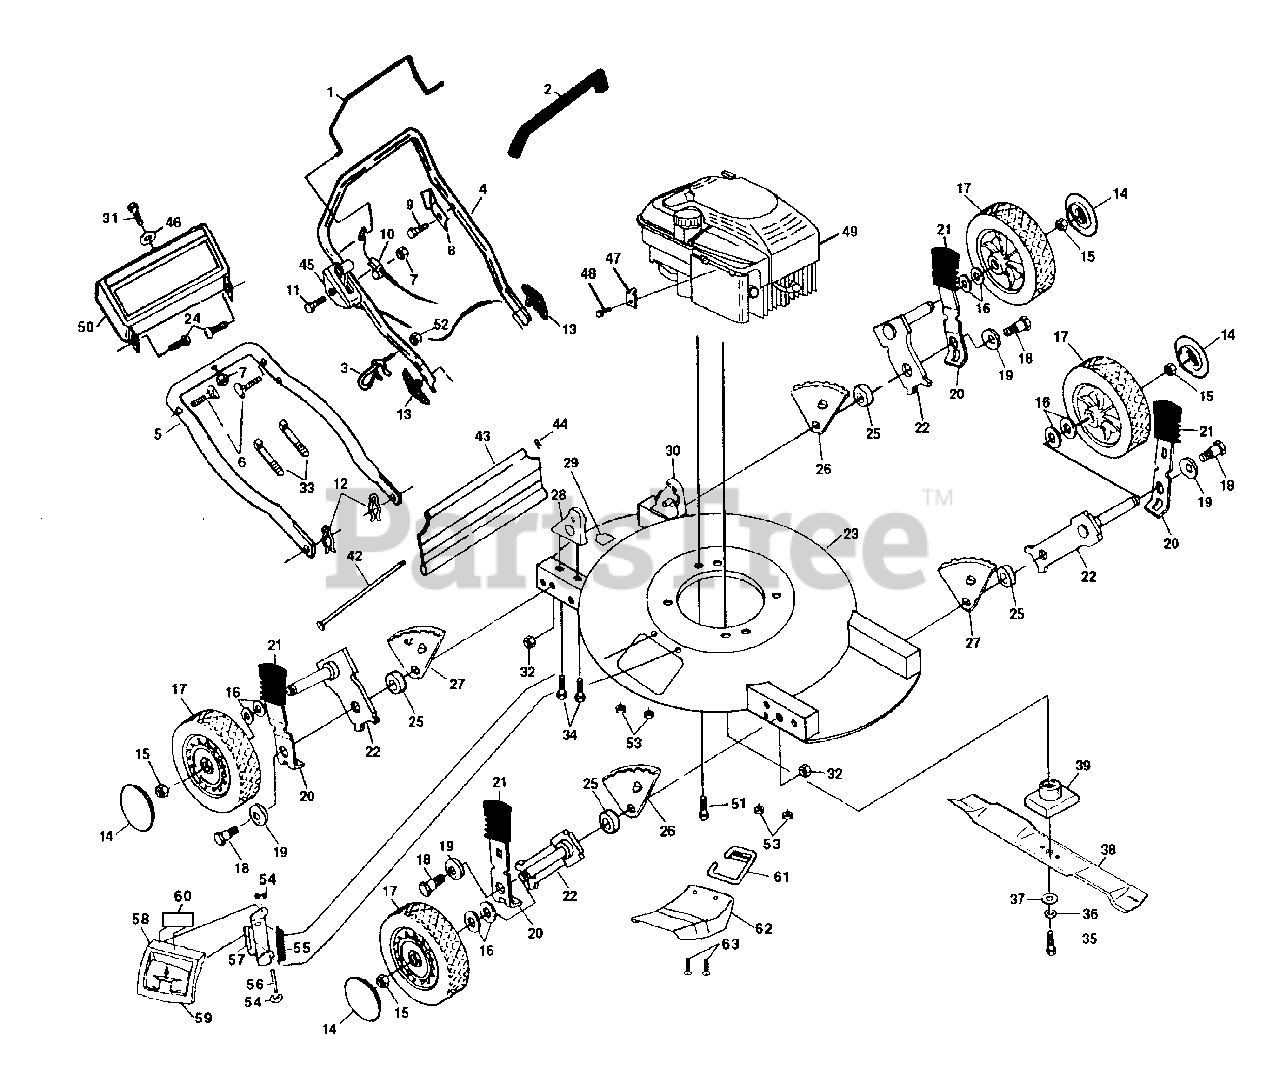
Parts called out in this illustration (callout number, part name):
1	Control Bar
2	Handle Grip
3	Rope Guide
4	Upper Handle
5	Lower Handle
6	Handle Bolt 5/16-18 x 1-3/4
7	Locknut 1/4-20
8	Up-Stop Bracket
9	Hex Washer Head Screw #10-24 x 1/2
10	Engine Zone Control Cable
11	Hex Washer Head Screw 1/4-20 x 2.12
12	Hairpin Cotter
13	Handle Knob
15	Hex Locknut 3/8-16
16	Washer
17	Wheel & Tire Assembly
18	Shoulder Bolt
19	Belleville Washer
20	Selector Spring
21	Selector Knob
22	Axle Arm Assembly
23	Lawn Mower Housing
25	Spacer
26	Wheel Adjusting Bracket (R.F./L.R.)
27	Wheel Adjusting Bracket (L.F./R.R.)
28	Handle Bracket Assembly (Right)
29	Danger Decal
30	Handle Bracket Assembly (Left)
31	Screw
32	Locknut 3/8-16
33	Wire Tie
34	Thread Cutting Screw 5/16-18 x 3/4
35	Hex Head Screw 3/8-24 x 1-3/8
36	Helical Lockwasher 3/8
37	Hardened Washer
39	Blade Adapter
42	Deflector Rod
43	Rear Deflector
44	Retainer Clip
45	Throttle Control
47	Cable Clamp
48	Thread Rolling Screw #10-32 x 5/8
50	Trim Plate
51	Hex Head Screw, Self Tap. 3/8 - 16 x 1.1
52	Keps Locknut 1/4-20
53	Locknut
54	External E-Ring
55	Torsion Spring
57	Housing Assembly Bracket
58	Mulcher Door
59	Door Latch
61	Chute Mounting Bracket
62	Mulcher Deflector
63	Truss Head Screw
